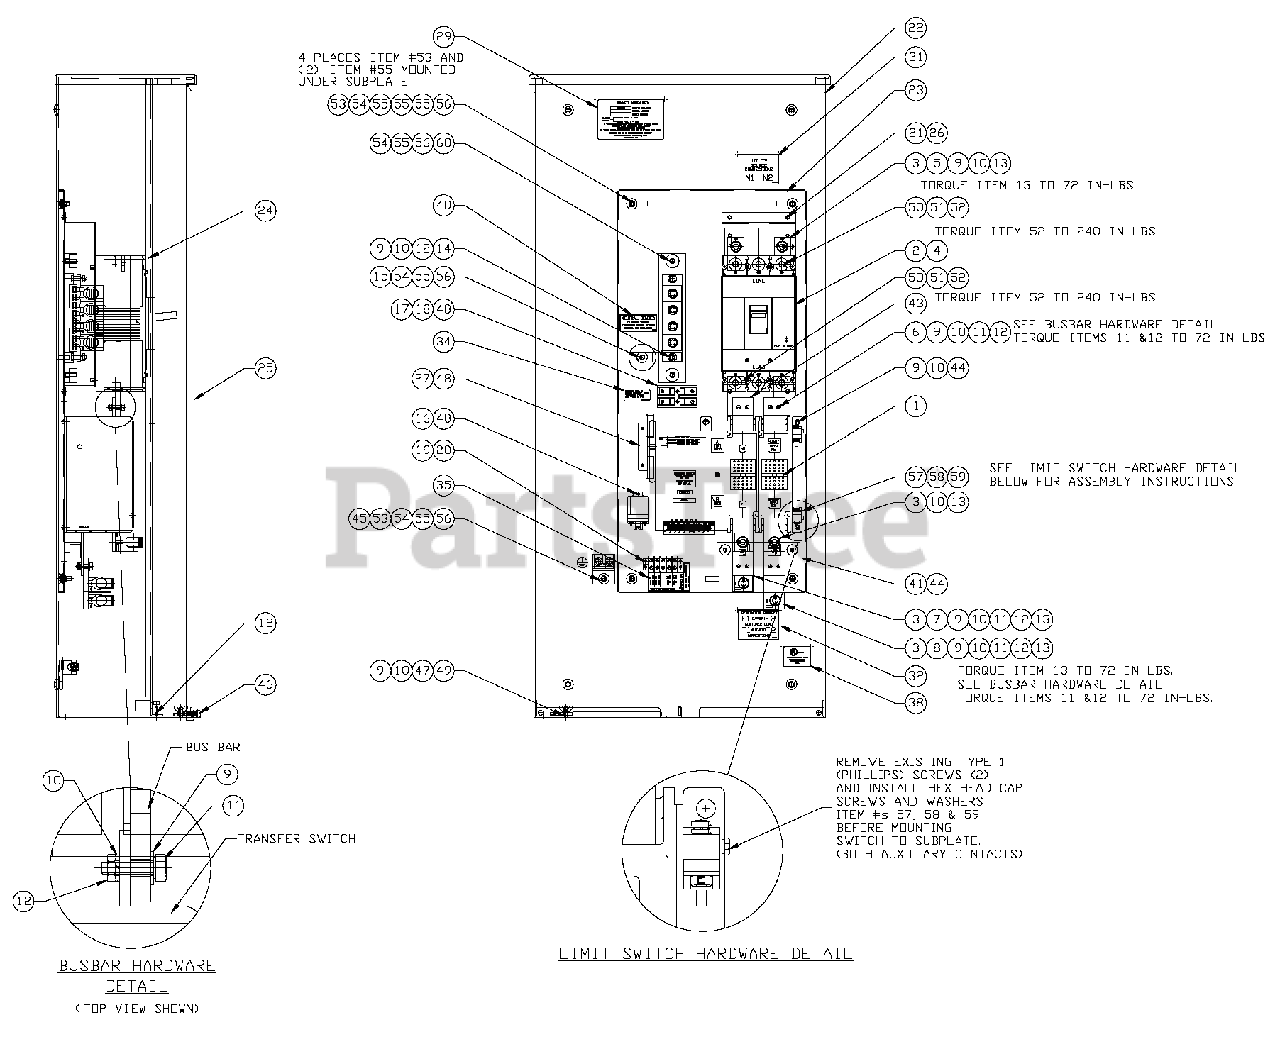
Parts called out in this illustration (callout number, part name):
1	TRANSFER SWITCH - W 400A 600V 2P
2	CB 0400A 2P 480V 400
3	LUG, SLDLSS 600/250-1/0X1/4-28
4	SCREW RHM 10-32 X 4
5	BUS BAR CB ADAPTER
6	BUSBAR 400A SE--N1,N2
7	BUSBAR 400A SE--T1
8	BUSBAR 400A SE--T2
9	WASHER FLAT 1/4-M6 ZINC
10	WASHER LOCK M6-1/4
11	SCREW HHC 1/4-20 X 1 G5
12	NUT HEX 1/4-20 STEEL
13	SCREW, HHCS 1/4-28 X 5/8"
17	FUSEBLOCK 30A 600V 2 POLE
18	FUSE 5A X BUSS HLDR73591
19	BLOCK TERM 20A 5 X 6 X 1100V
20	RIVET, POP .156 X .67
21	SCREW HHTT M6-1.0 X 12 ZINC
22	WELDMENT 3R 400A SE ENCLOSURE
23	SUBPLATE 400A SE 3R ENCL
26	RISER, 400A CIRCUIT BREAKER
27	BRACKET, TRANSFER SWITCH HANDLE
28	DECAL, TRANSFER SWITCH RTS SE
29	DECAL, DATA XFER SW SD 400A
33	DECAL, UTILITY DISCONNECT
34	DECAL, FUSE REPLACEMENT
35	DECAL, TERMINAL STRIP
40	DECAL, NEUTRAL CONNECTION
41	BUSBAR SPACER 400A SE T1,T2
43	SCREW HHTT M4-0.7 X 1/4 CZ
44	SCREW HHTT M6-1.0 X 20 BP
45	LUG SOLDERLESS 250-#6 X 11MM AL/CU
46	THUMB SCREW 1/4-20x1/2
47	HANDLE TRANSFER SWITCH 1-400A
48	SCREW HHTT M4-.7 X 8 BP
49	NUT WING 1/4-20
50	WASHER LOCK M10
51	WASHER FLAT 3/8-M10 ZINC
52	SCREW SHC M10-1.5 X 25 G12.9
53	WASHER LOCK SPECIAL 5/16
54	WASHER LOCK M8-5/16
55	WASHER FLAT 5/16-M8 ZINC
56	NUT HEX 5/16-18 STEEL
60	ASS'Y NEUTRAL BLOCK 300-400A
